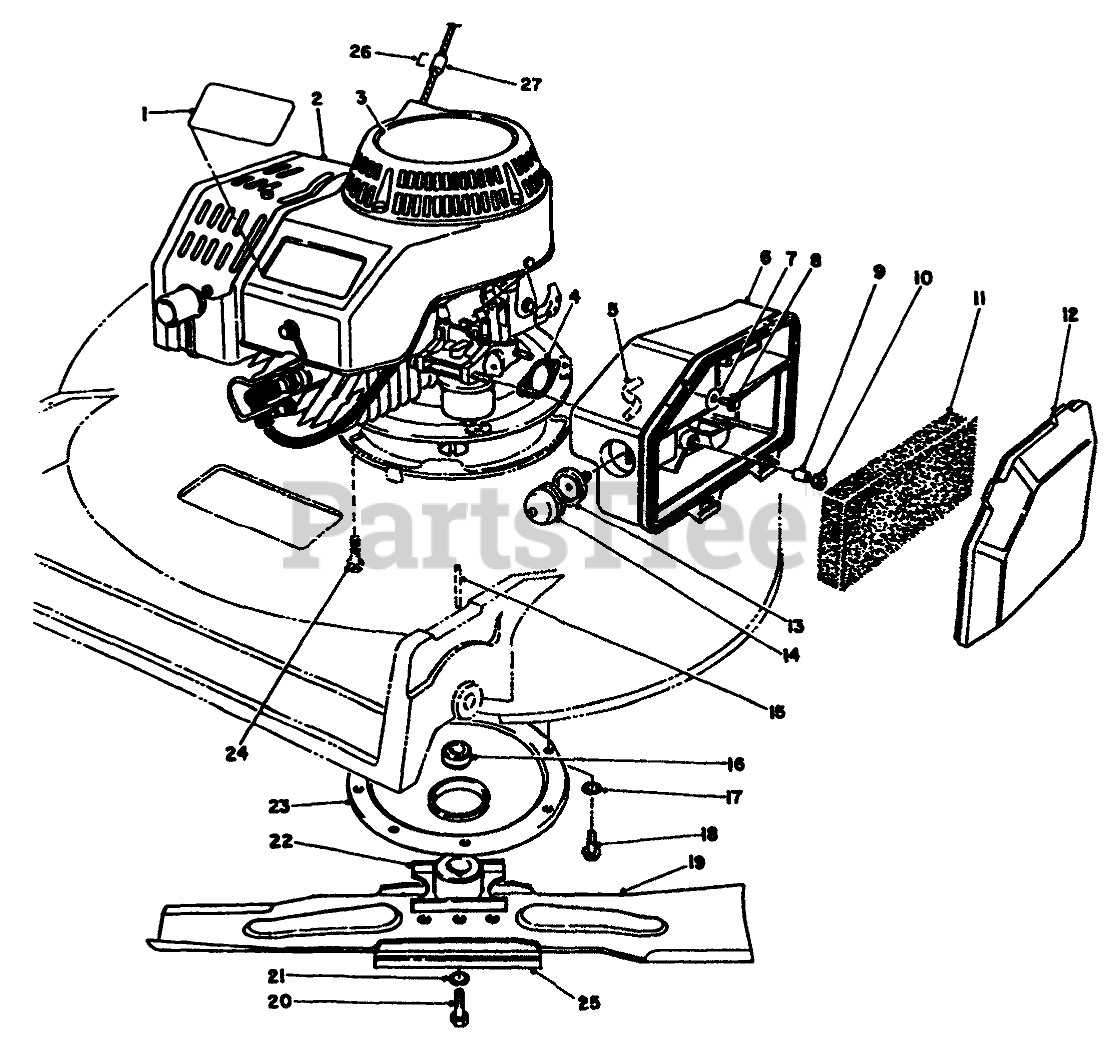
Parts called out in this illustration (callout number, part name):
1	DECAL - PROLINE
2	ENGINE ASM
3	DECAL-2 CYC RECOIL COMM
4	GASKET-AIR CLEANER
5	HOSE-PRIMER
6	BODY-AIR CLEANER
7	WASHER-FLAT
8	SCREW-HH
9	SPACER
11	ELEMENT-AIR CLEANER
12	COVER-AIR CLEANER
13	BODY-PRIMER
14	BULB-PRIMER
15	KEY-SQUARE
16	SPACER-BLADE RETAINER
17	WASHER-LOCK, INTERNAL
18	SCREW-HWHTF
19	Blade
20	SCREW-BLADE
21	WASHER-LOCK
22	RETAINER-BLADE
23	PROTECTOR-CRANKSHAFT
24	SCREW-HHF
25	Accelerator
26	Staple
27	STOP-ROPE
